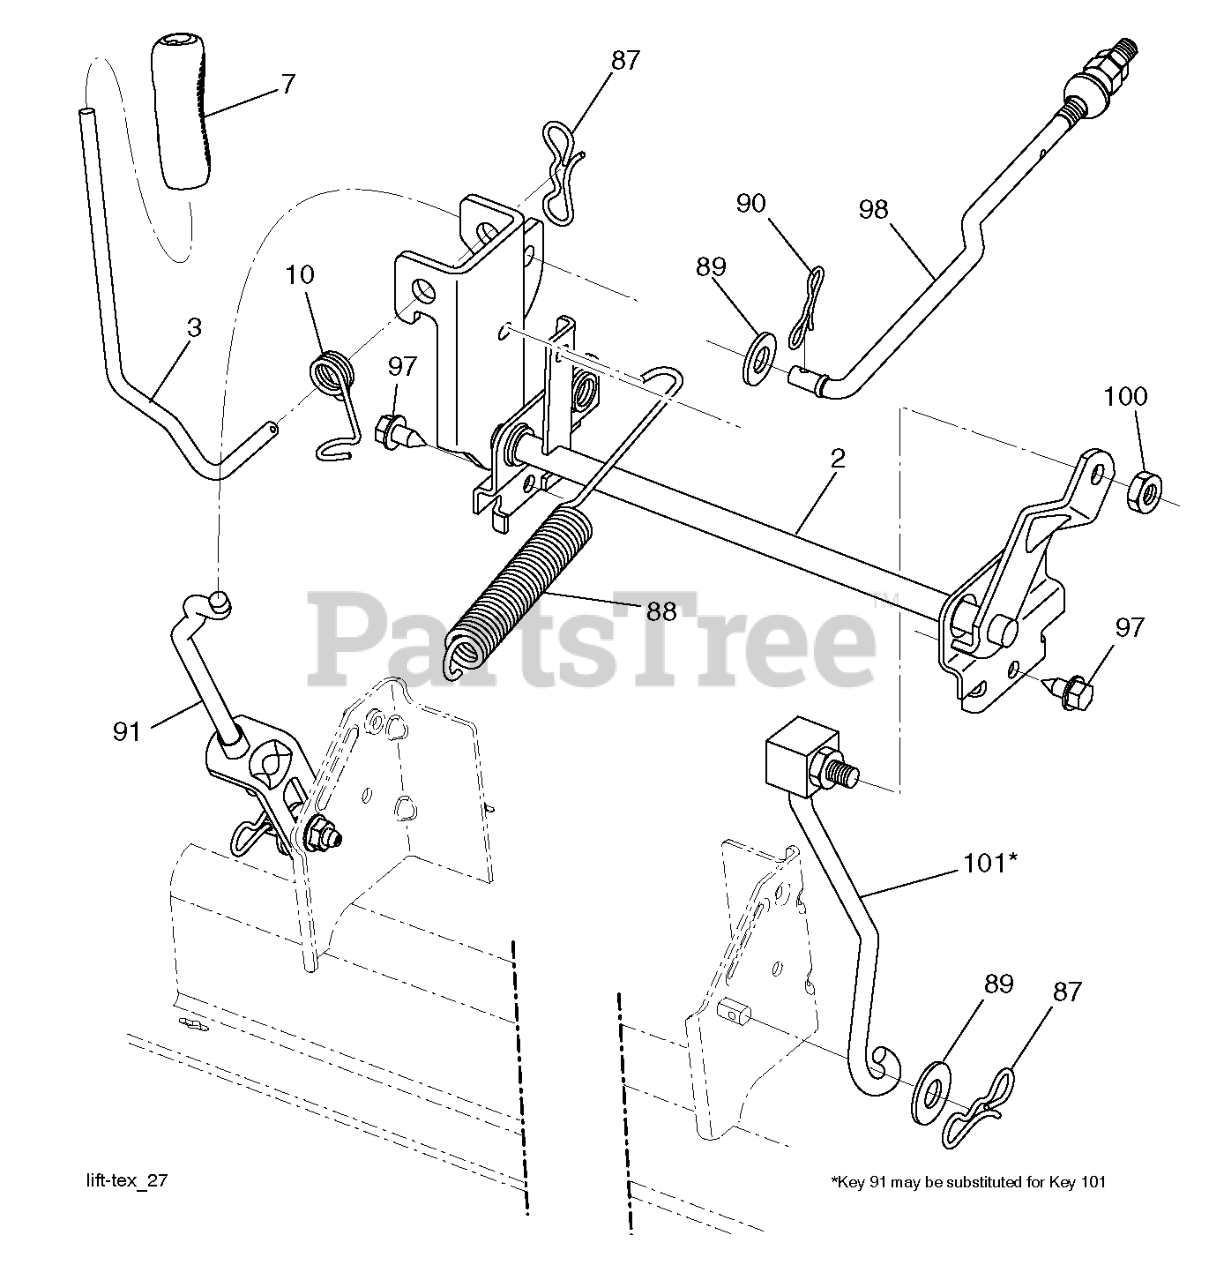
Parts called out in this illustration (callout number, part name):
2	SHAFT LIFT DECK WELD
3	LEVER.LIFT.HANDLE.LT
7	GRIP.HANDLE.LIFT.PVC.BLACK
10	SPRING.TORSION.LIFT.HANDLE
87	PIN.COTTER.7/16.BOW TI.
88	SPRING SPRING LIFT ASSIST 97
89	WASHER.CLEAR.ZINC
90	PIN.COTTER.5/16.BOW TI
91	LINK.ASM.LIFT.REAR
97	SCREW LT
98	LINK.ASM.SUSP.FRONT.MW
100	LOCKNUT
101	LINK.ASM.LIFT.FIXE.38/42/46"
